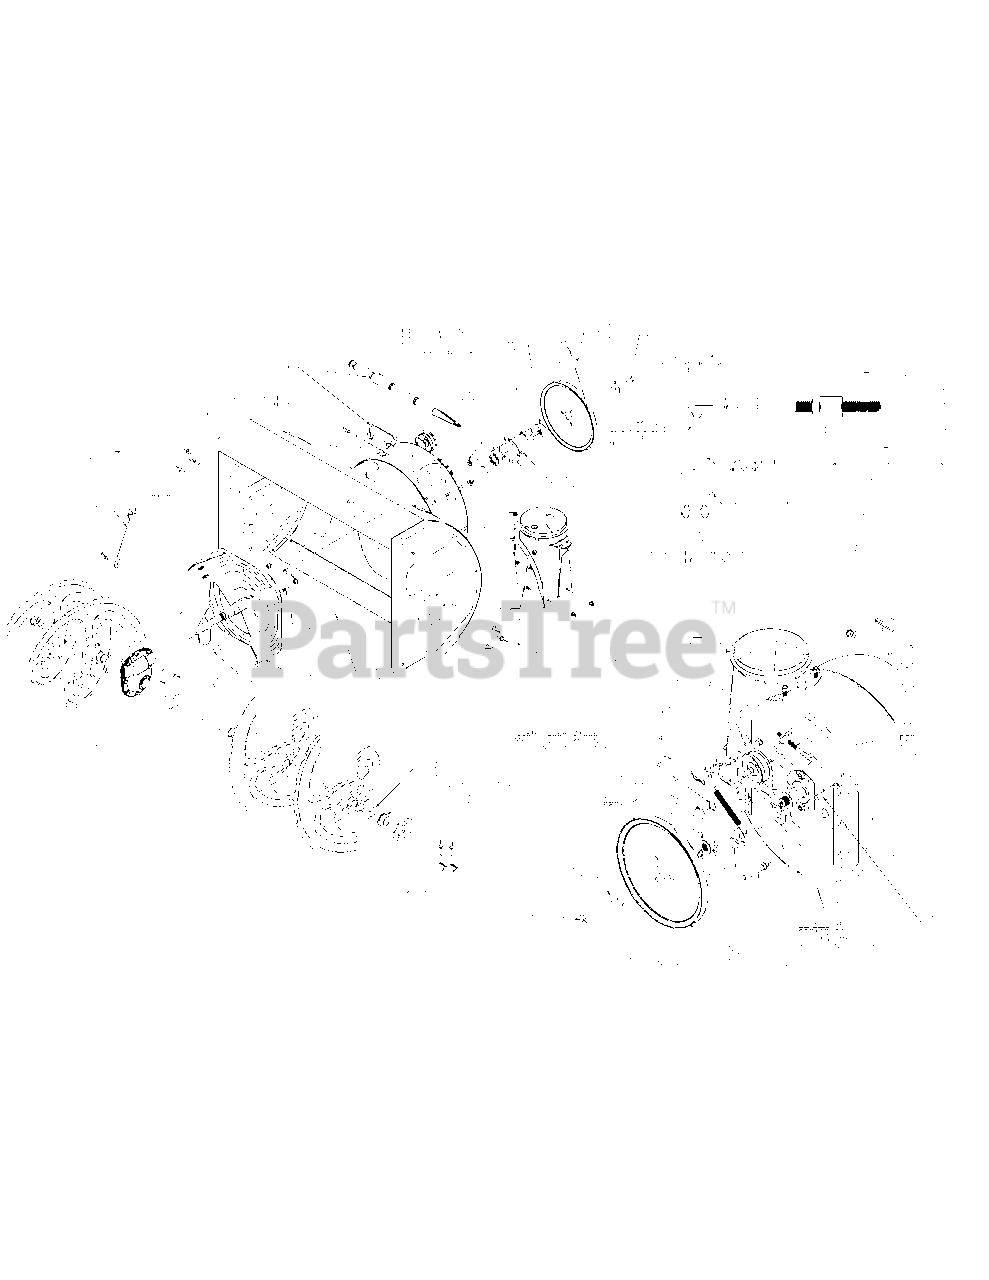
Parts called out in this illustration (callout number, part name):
1	Bracket Assy-Br
2	Impeller Asm-16"
3	Tool-Cleanout
3	Clip-Tool Mtg
4	Screw-Hex Cap 5
6	Carriage Bolt 5/16-18 X .75
7	Screw-5/16-18 Tt
8	Screw-Hex Cap 5/1
9	Engagement Ferru
10	Nut-Flglk 5/16-18
11	Nut-Flange Lk.Nylo
12	Nut-Hex Jam
13	Key-Woodruff #91
14	Pin-Cotter
15	Pin-Spring Spir
16	Tie-Cable 7"
17	Nut-Push On
18	Chute Adapter
19	Spring-Extension
20	Washer-Fl
21	Washer-Wave .660 I
22	Washer-Fl-.760Id X
23	Washer-Fl
24	Washer-Fl.344
25	Washer-Flat
26	Grease
27	Screw-Shld .625
28	Shear Pin .25X150
29	Bearing-Flange
30	Bearing-Self-Al
31	Rod-Auger Idler
32	Pulley-Adapter .75
34	Pulley-Auger 10.0
36	Bearing Housing
